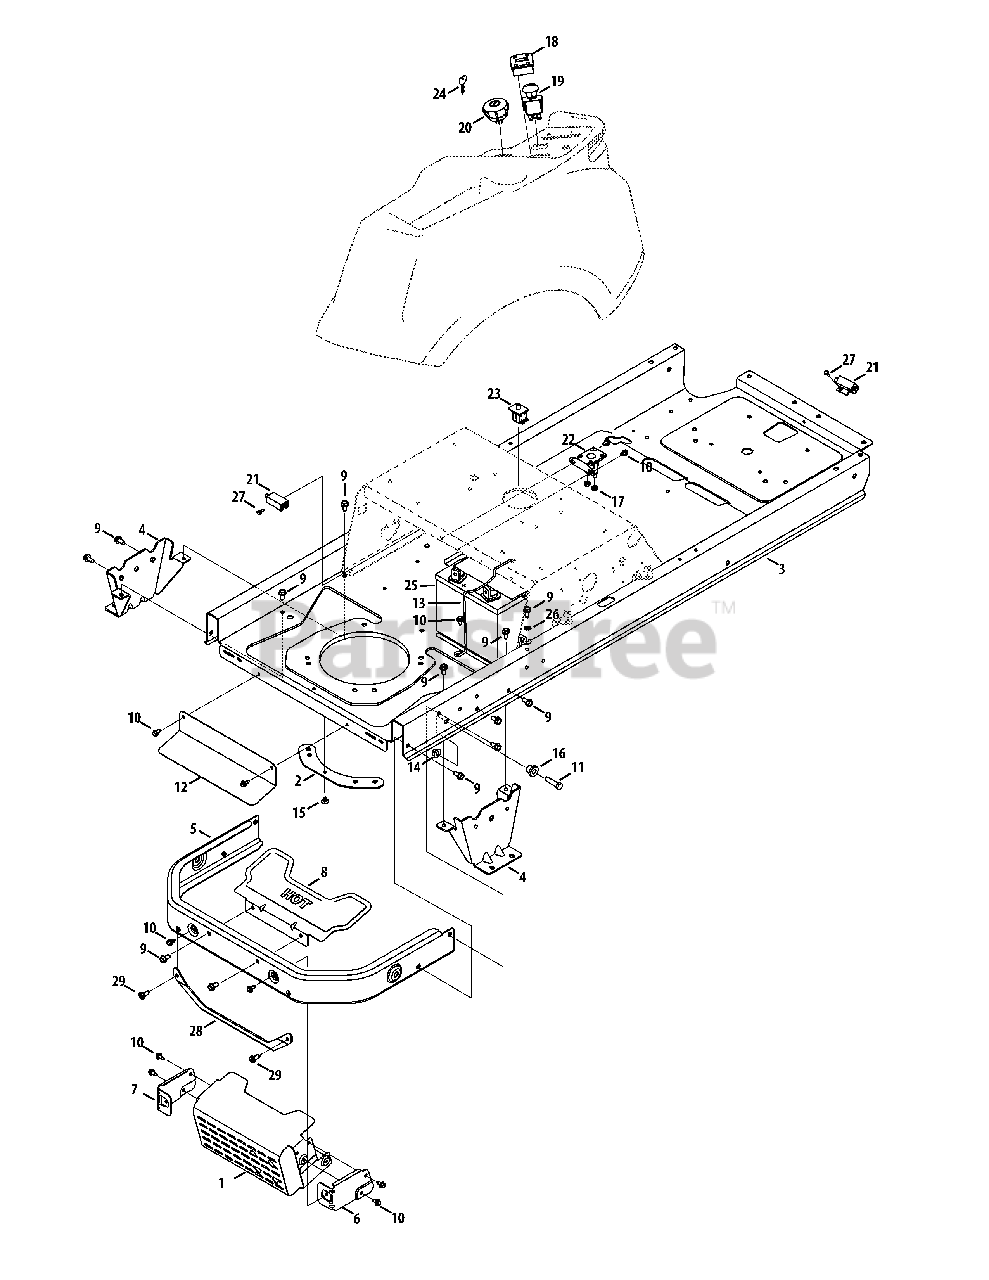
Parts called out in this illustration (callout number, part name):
1	Muffler Shield Assembly
2	Retainer Plate
3	Frame Assembly
4	Transmission Mounting Bracket
5	Rear Bumper
6	Muffler Mounting Shield Bracket, RH
7	Muffler Mounting Shield Bracket, LH
8	Muffler Shield
9	Hex Washer Screw, 5/16-18 x .750
10	Hex Washer Screw, 1/4-20 x .625
11	Hex Screw, 3/8-16 x 1.25
12	Lower Heat Shield
13	Battery Rod
14	Flange Lock Nut, 3/8-16
15	Clip, .250 Dia. x .500 LG
16	Shoulder Spacer, .38 x 1.0 x .70
17	Flange Lock Nut, 1/4-20
18	Hour Meter/Service Minder
19	Electric PTO Switch
20	Key Switch
21	Interlock Switch
22	Solenoid
23	Seat Switch
25	Battery
26	Lock Washer, 5/16
27	Shoulder Screw, #10-32 x .500
28	Rear Muffler Shield Bracket
29	Screw, Self-Tapping, 5/16-18, 0.750
